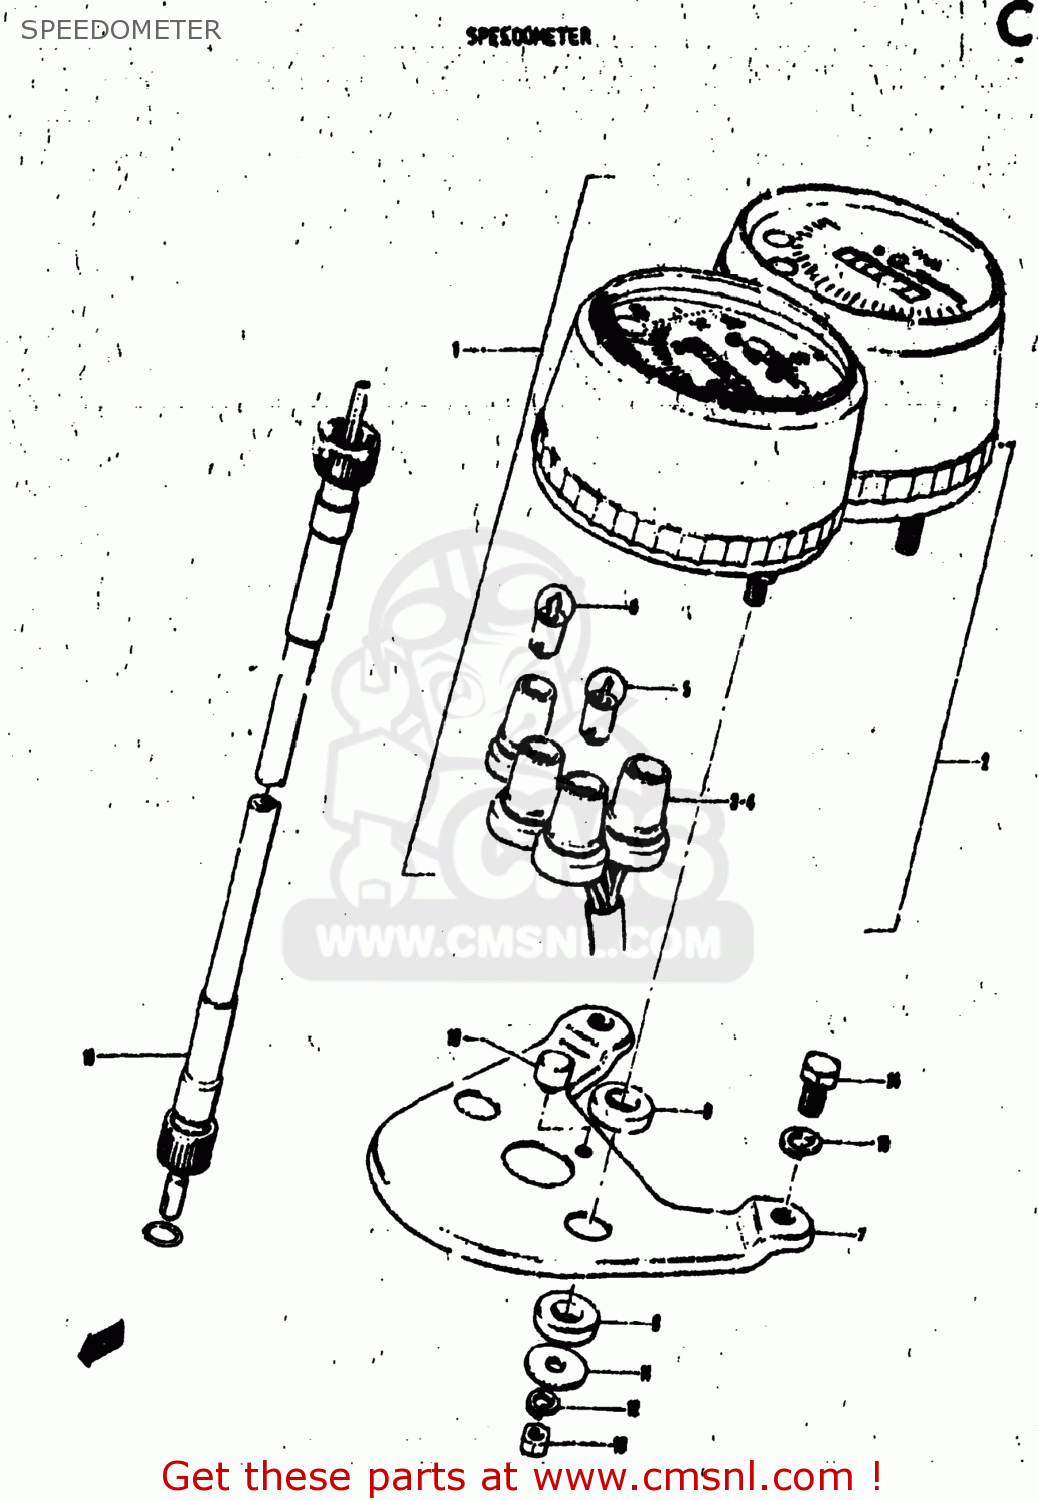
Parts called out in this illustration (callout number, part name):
1	SPEEDOMETER ASSEMBLY
2	SPEEDOMETER ASSEMBLY
3	SOCKET ASSY MT50R
4	SOCKET,METER
5	BULB(6V/3W)
6	BULB(6V1.7W,STANLEY,A61A)
8	CUSHION,METER
9	CUSHION
10	CUSHION,METER
11	WASHER(5.5X16X1.5)
12	LOCK WASHER
13	NUT
14	BOLT
15	WASHER,LOCK
16	CABLE ASSEMBLY,SPEEDOMETER
